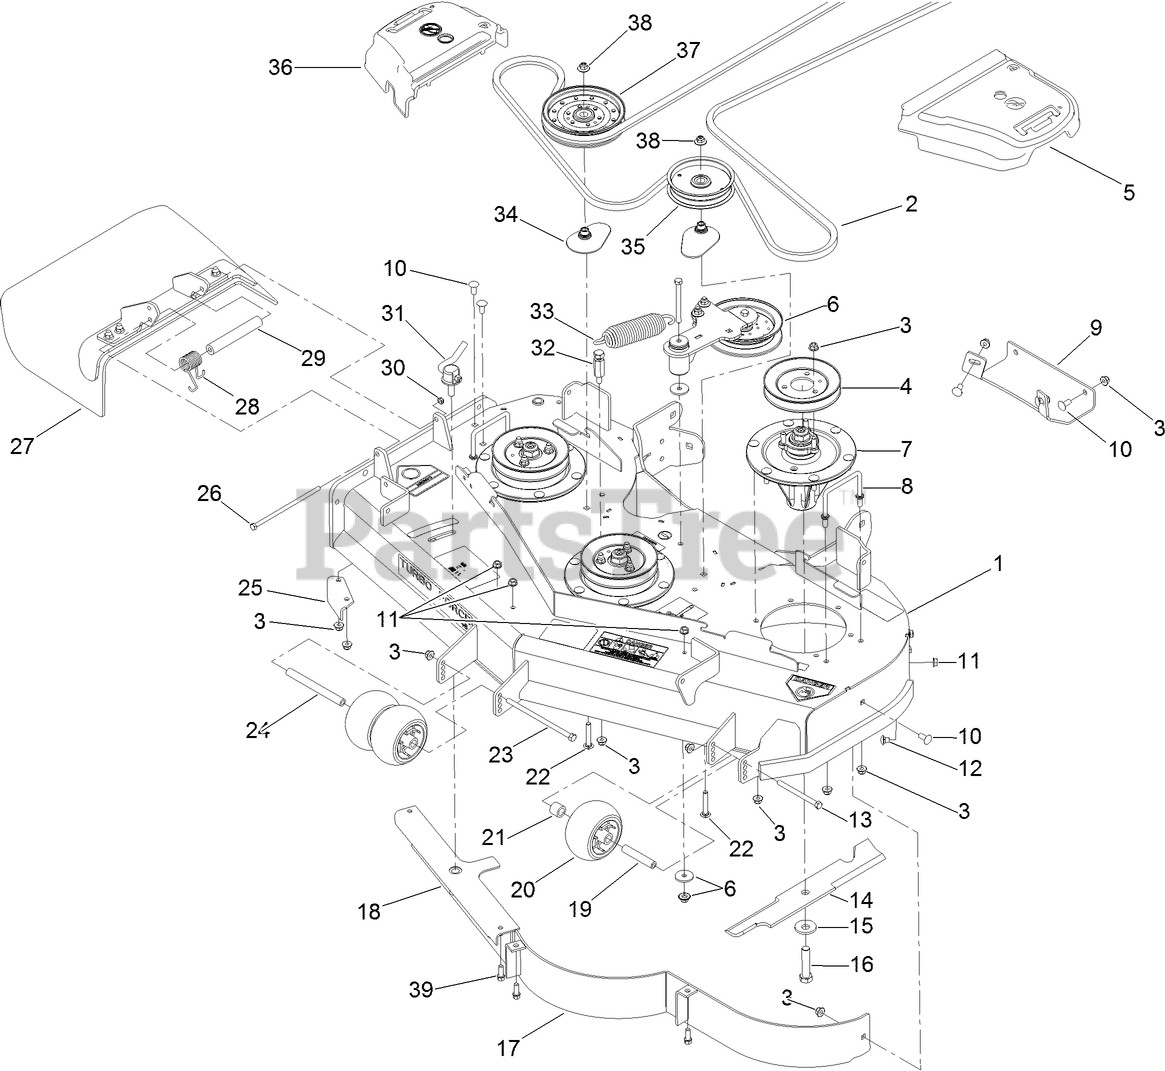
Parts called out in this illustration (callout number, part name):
1	DECK DECAL ASM
2	BELT-V
3	NUT-HF, NI
4	PULLEY
5	COVER-BELT, LH
6	IDLER ARM ASM
7	SPINDLE ASM
8	WIREFORM-COVER
9	PLATE-SKID
10	SCREW-CARR
11	NUT-HHF, WHIZ
12	SCREW-CARR
13	SCREW-HH
14	BLADE-16.5 INCH (HIGH FLOW)
15	Washer-Blade Bolt, Heavy
16	SCREW-BLADE
18	BAFFLE
19	TUBE-SPANNER
20	ROLLER-SCALP, ANTI
21	TUBE-SPACER
22	BOLT-CARR, SHORT NECK
23	SCREW-HH
24	SPACER-WHEEL
25	BAFFLE-DISCHARGE
26	SCREW-HH
27	RUBBER DEFLECTOR ASM
28	SPRING-TORSION
29	SPACER
30	NUT-LOCK, NI
31	LEVER ASM
32	ANCHOR-SPRING, TALL
33	EXTENSION-SPRING
34	SPACER-PULLEY
35	PULLEY-IDLER
36	COVER-BELT, RH
37	PULLEY-IDLER, FLAT
38	NUT-FLANGE, NI
39	SCREW-HWH
